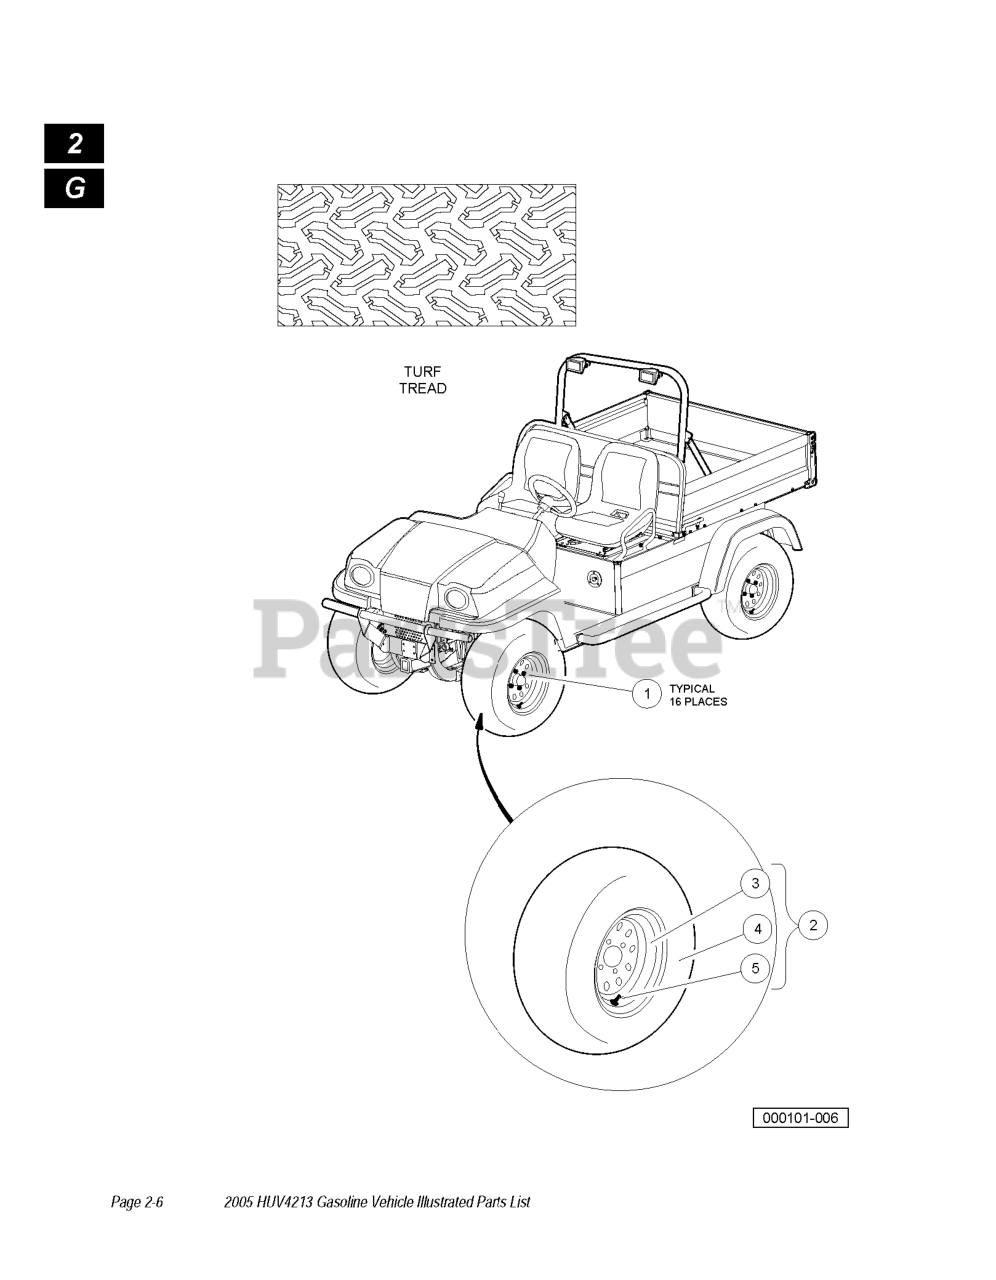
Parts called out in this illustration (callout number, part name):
1	NUT 1/2-20 LUG
2	Gray Tire Assembly, Turf Tread
3	WHEEL RIM, GRAY
